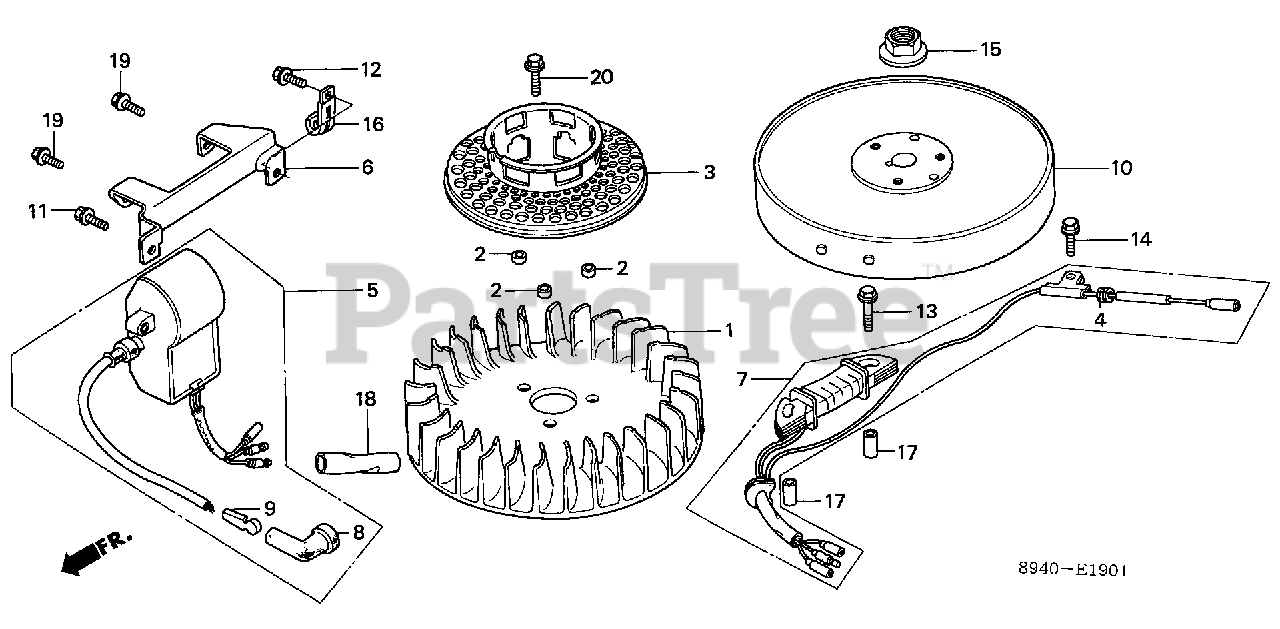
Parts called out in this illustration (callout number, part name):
1	FAN, COOLING
2	COLLAR, FAN
3	PULLEY, STARTER
4	GROMMET, PRIMARY WIRE
5	MODULE, IGNITION CONTROL (CDI)
6	STAY, IGNITION CONTROL MODULE
7	COIL ASSY., EXCITER
8	CAP, IGNITION (TOYO)
9	TERMINAL, PLUG
10	FLYWHEEL (C.D.I.)
11	BOLT, FLANGE (6X12) (CT200)
12	BOLT, FLANGE (6X14) (CT200)
13	BOLT, FLANGE (6X28)
14	BOLT, FLANGE (5X10)
15	NUT, SPECIAL (14MM)
16	CLIP, CABLE
17	PIN A, DOWEL (8X14) (YAMADA)
18	TUBE, VINYL (16X19X50)
19	BOLT, FLANGE (6X12)
20	BOLT, FLANGE (6X16)
